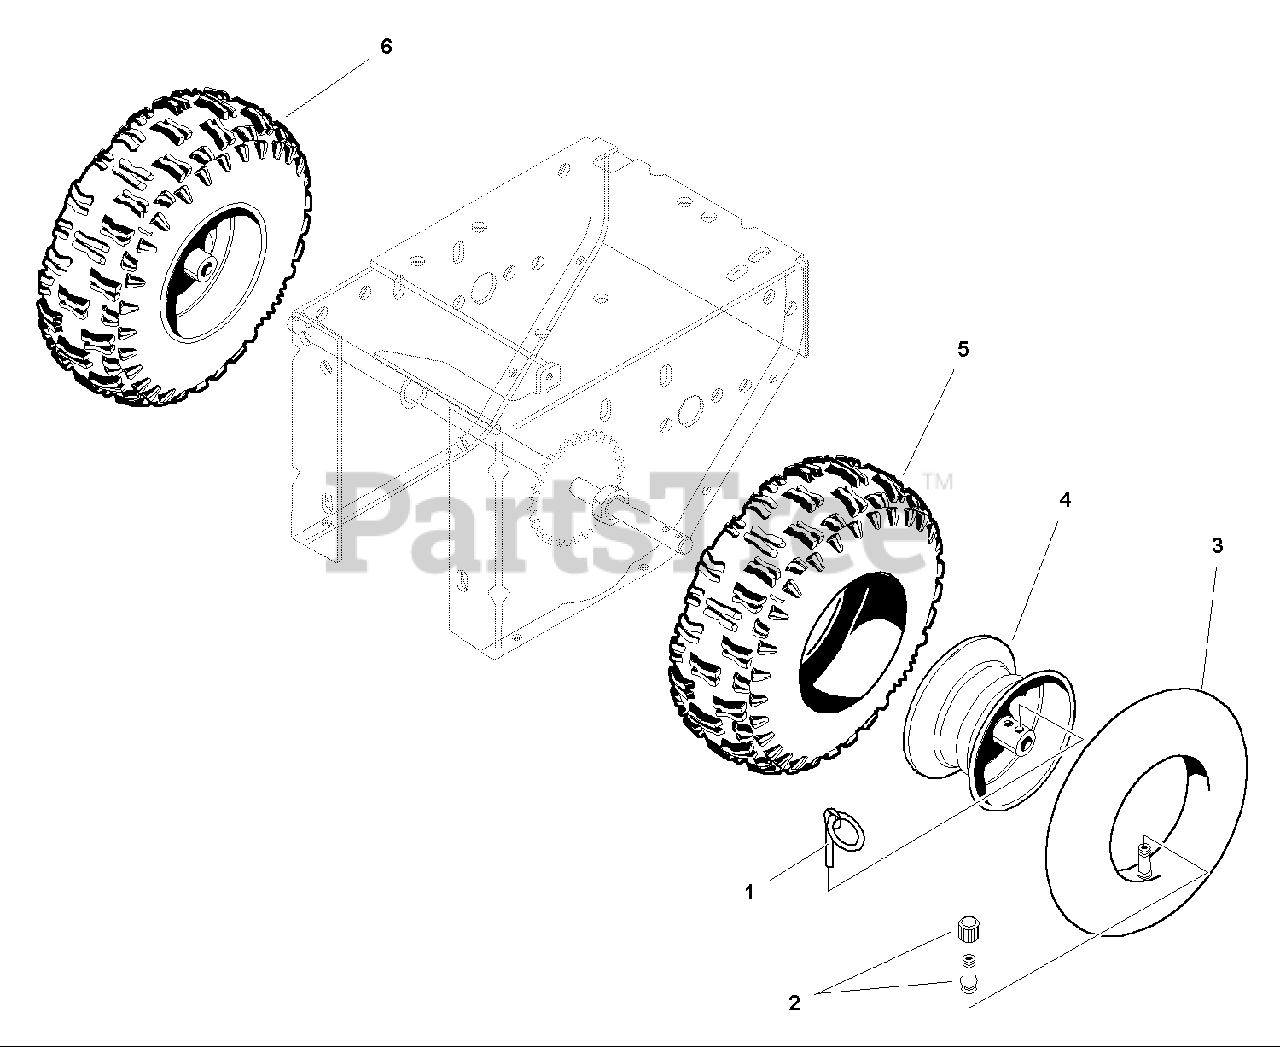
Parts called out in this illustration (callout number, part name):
2	VALVE STEM & CAP
6	*WHEEL & TIRE ASSEMBLY, (Includes Ref. 2-5)
6	**WHEEL & TIRE ASSEMBLY, (Includes Ref. 2-5)
